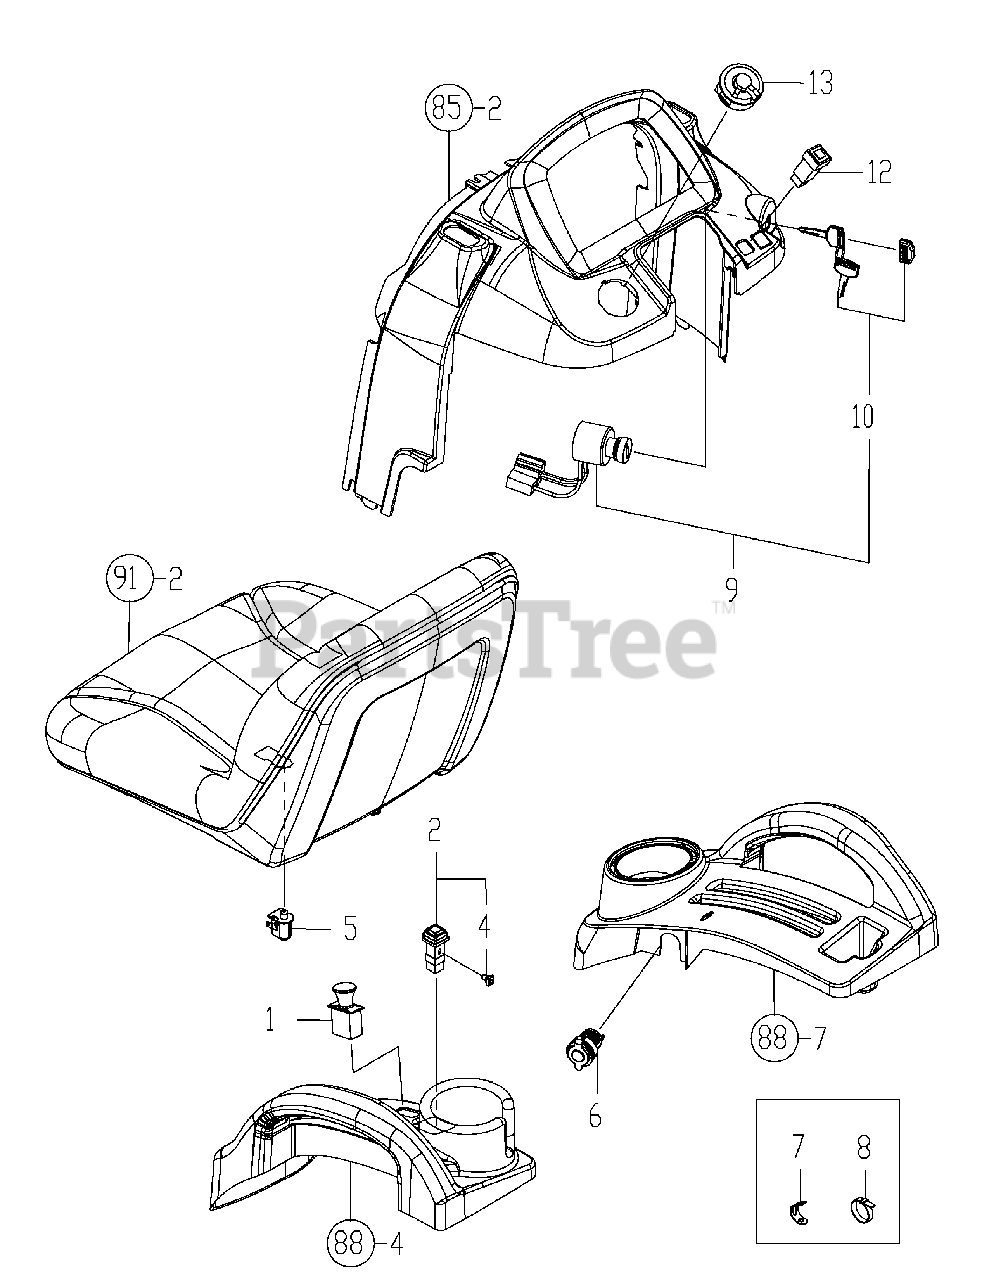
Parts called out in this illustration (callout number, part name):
5	SWITCH, SEAT, DELTA, AS
6	DC POWER OUTLET
7	CLAMP, WIRING
8	BAND, 140
9	SWITCH, ASSY STARTER
13	SWITCH, COMBINATION
